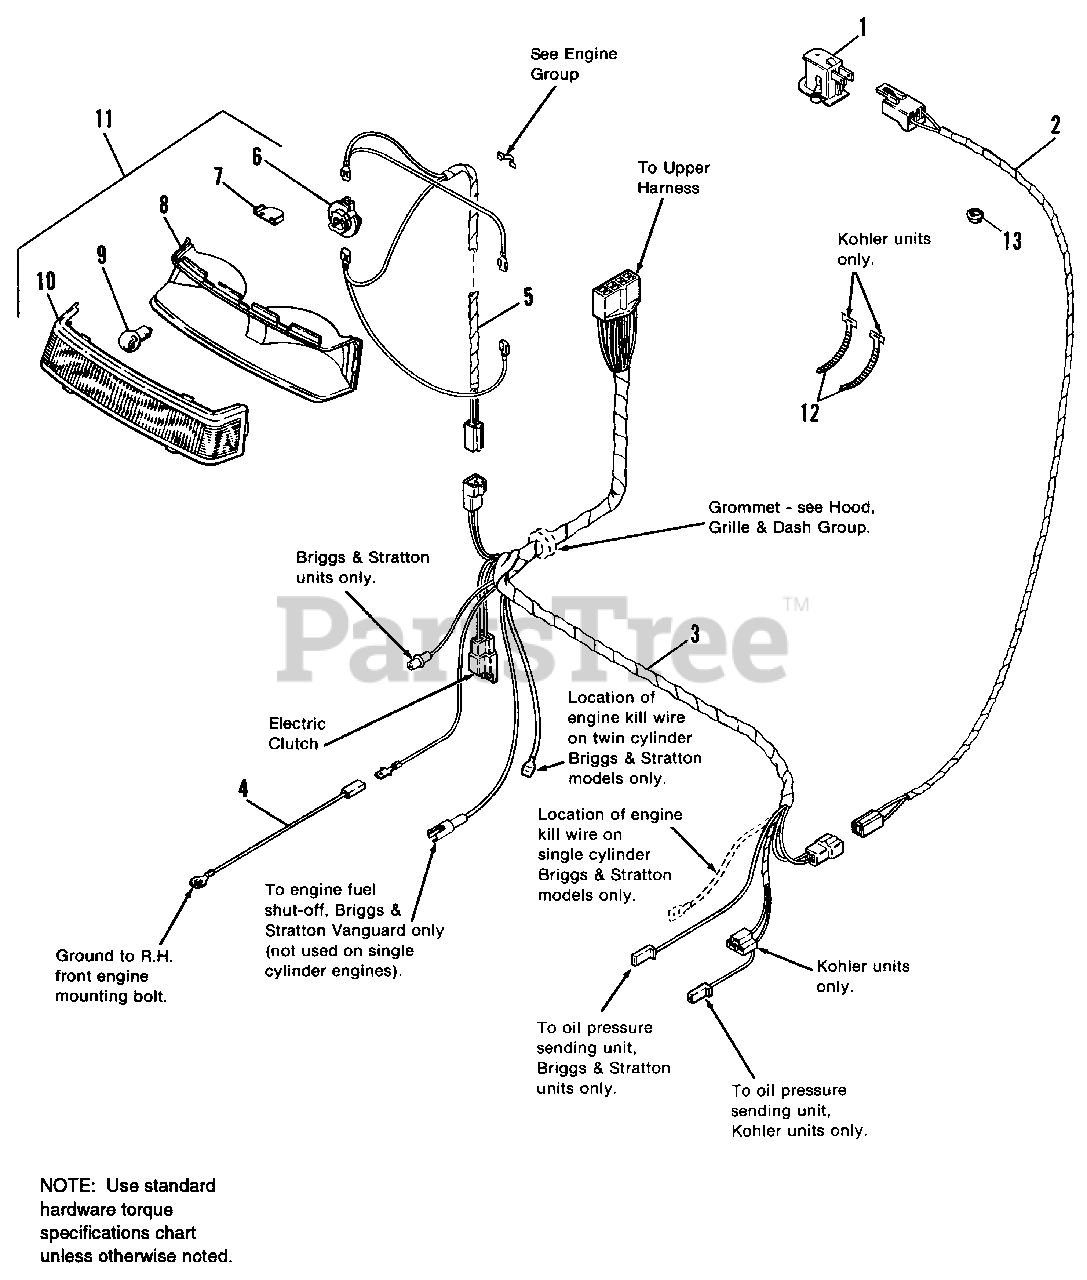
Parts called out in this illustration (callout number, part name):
1	SWITCH, Seat, Operator Present
2	WIRE ASSY., Seat Switch
3	HARNESS ASSY., Lower (Twin Cylinder Briggs & Stratton Vanguard)
3	HARNESS ASSY., Lower (Single Cylinder Kohler Command)
3	HARNESS ASSY., Lower (Single Cylinder Briggs & Stratton)
4	WIRE ASSY., Engine Ground
5	WIRE ASSY., Headlight
6	SOCKET, Bulb
7	HEAT SHIELD
8	BEZEL, Headlight
9	BULB, Headlight, 12.8V
10	LENS, Headlight
11	HEADLIGHT ASSY. (Incl. Ref. Nos. 6-10)
13	BUSHING, Snap (Qty. 2 on 12.5 HP Hydro, Qty. 1 on 12.5 HP Gear)
